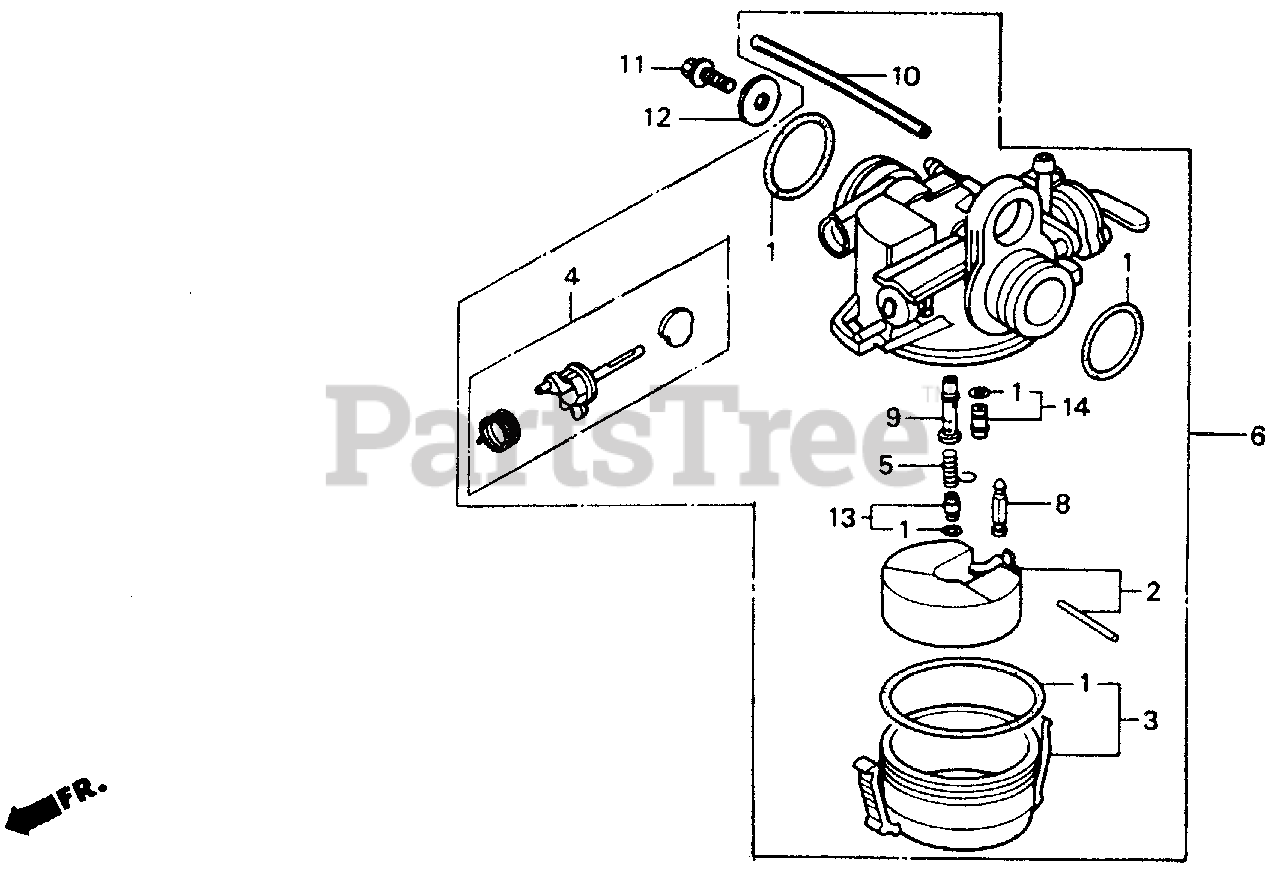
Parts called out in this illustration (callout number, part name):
1	GASKET SET
2	FLOAT SET (NOT AVAILABLE)
3	CHAMBER SET, FLOAT
5	SPRING, COIL (NOT AVAILABLE)
6	CARBURETOR ASSY.
8	VALVE, FLOAT
9	NOZZLE, MAIN (NOT AVAILABLE)
10	TUBE, VINYL (NOT AVAILABLE)
11	BOLT, FLANGE (6X12) (CT200)
12	WASHER, PLAIN (6MM)
13	JET SET, MAIN (#42)
13	JET SET, MAIN (#45)
13	JET SET, MAIN (#48)
14	JET SET, SLOW (#40)
